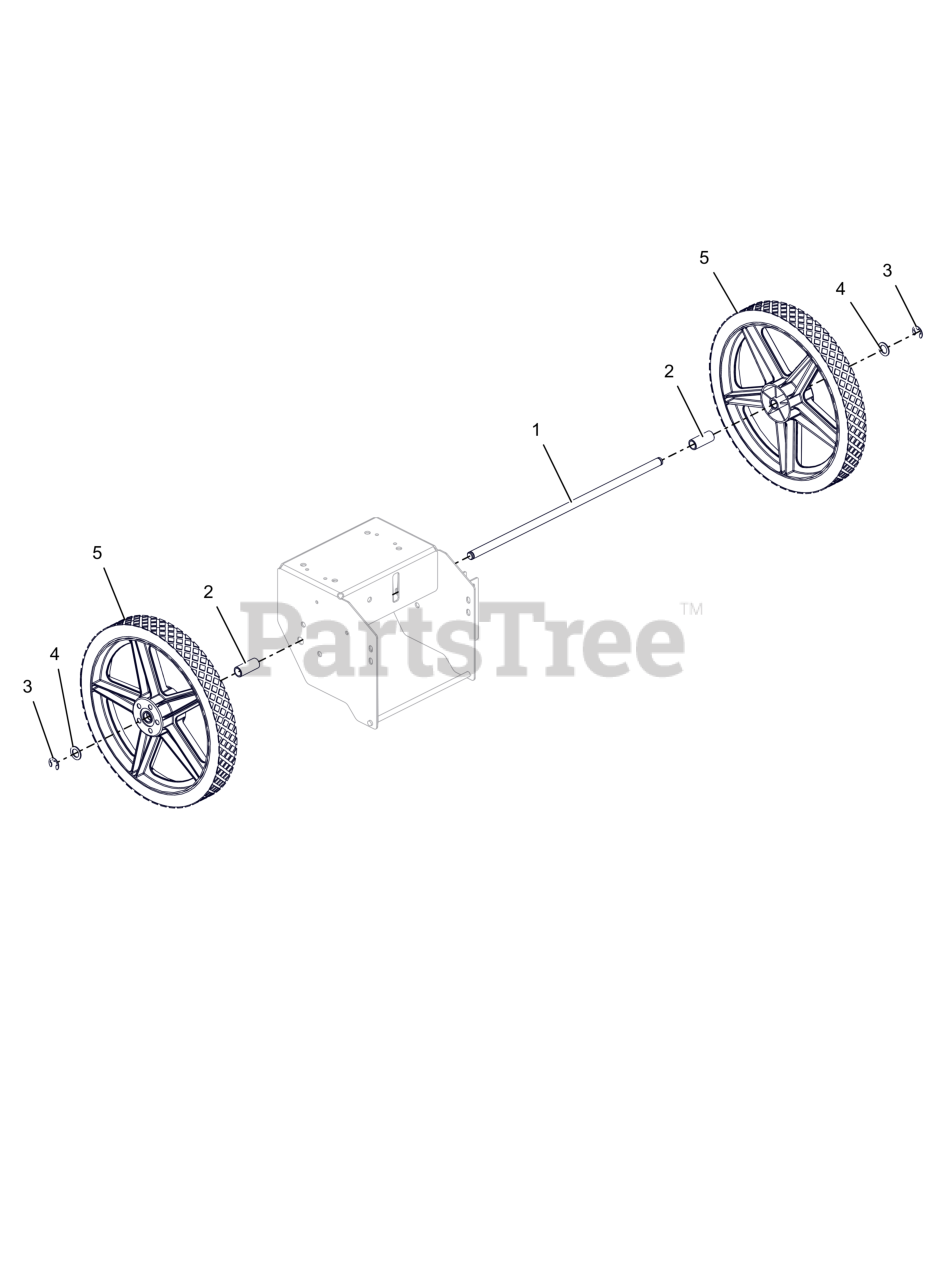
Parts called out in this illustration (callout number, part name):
2	SPACER, AXLE .571X.755X1.815
3	RG-RTNG-EXT .625X.042
4	WSHR, FLT .630X1.005X.062 ZCC
5	WHEEL, 14.000 X 1.750 X .565
